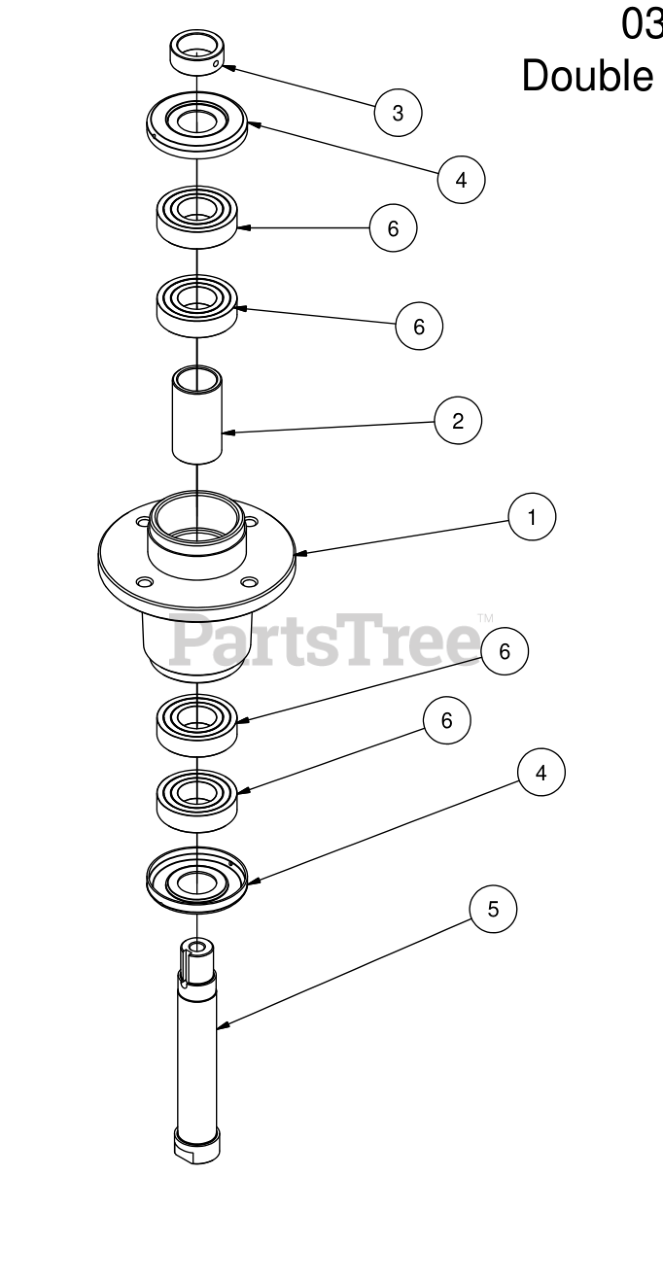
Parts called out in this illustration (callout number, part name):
1	4000 Series Spindle Housing
2	4000 Series Spindle Spacer
3	Locking Collar w/ 1/4"-20 Set Screw
4	Spindle Dust Cap
5	ZT-AOS Spindle Shaft
6	Bearing-6206
